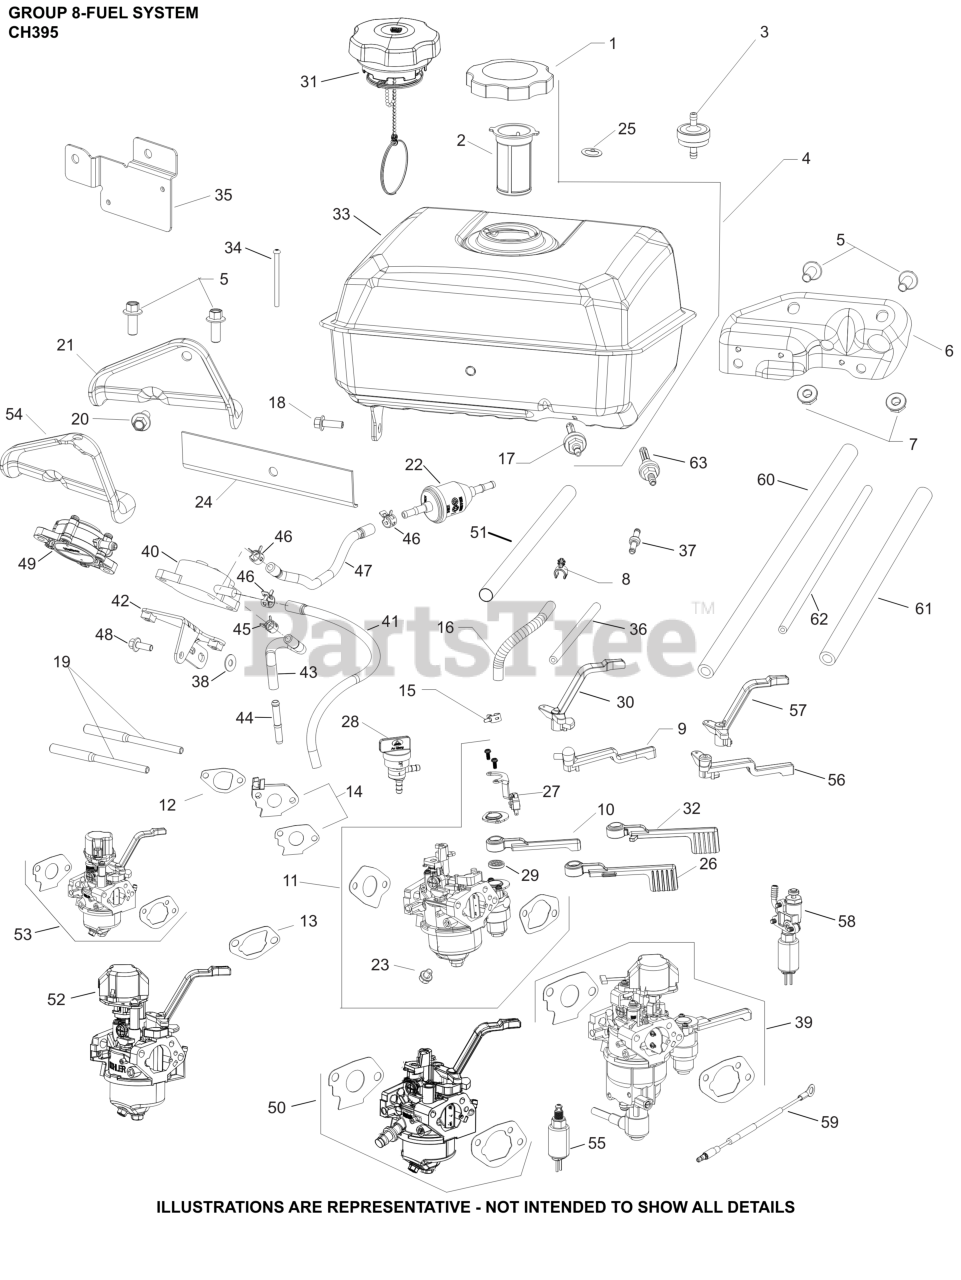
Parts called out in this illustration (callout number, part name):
1	CAP, FUEL TANK
2	FILTER, FUEL TANK
5	SCREW, M8 X 20
6	BRACKET, FUEL SUPPORT ASSEMBLY
7	NUT, FLG M8X1.25
8	CLIP, FUEL HOSE
11	KIT, CARBURETOR COMPLETE
12	KIT, INTAKE GASKETS
14	INSULATOR AND GASKET KIT
15	CLAMP, FUEL LINE
16	LINE, FUEL (10"-CUT TO LENGTH)
18	SCREW, M6 X18
19	STUD, CARBURETOR
20	SCREW, FLG 8X1.25X16
25	KIT, FUEL SCREEN
29	SEAL, INLET VALVE
33	TANK, FUEL
54	BRACKET, FUEL SUPPORT
63	FITTING, FUEL ASSY
NI	KIT, HIGH ALT (4000-8000 FT)
NI	KIT, HIGH ALT (8,000+ FT)
NI	KIT, CARBURETOR REPAIR
